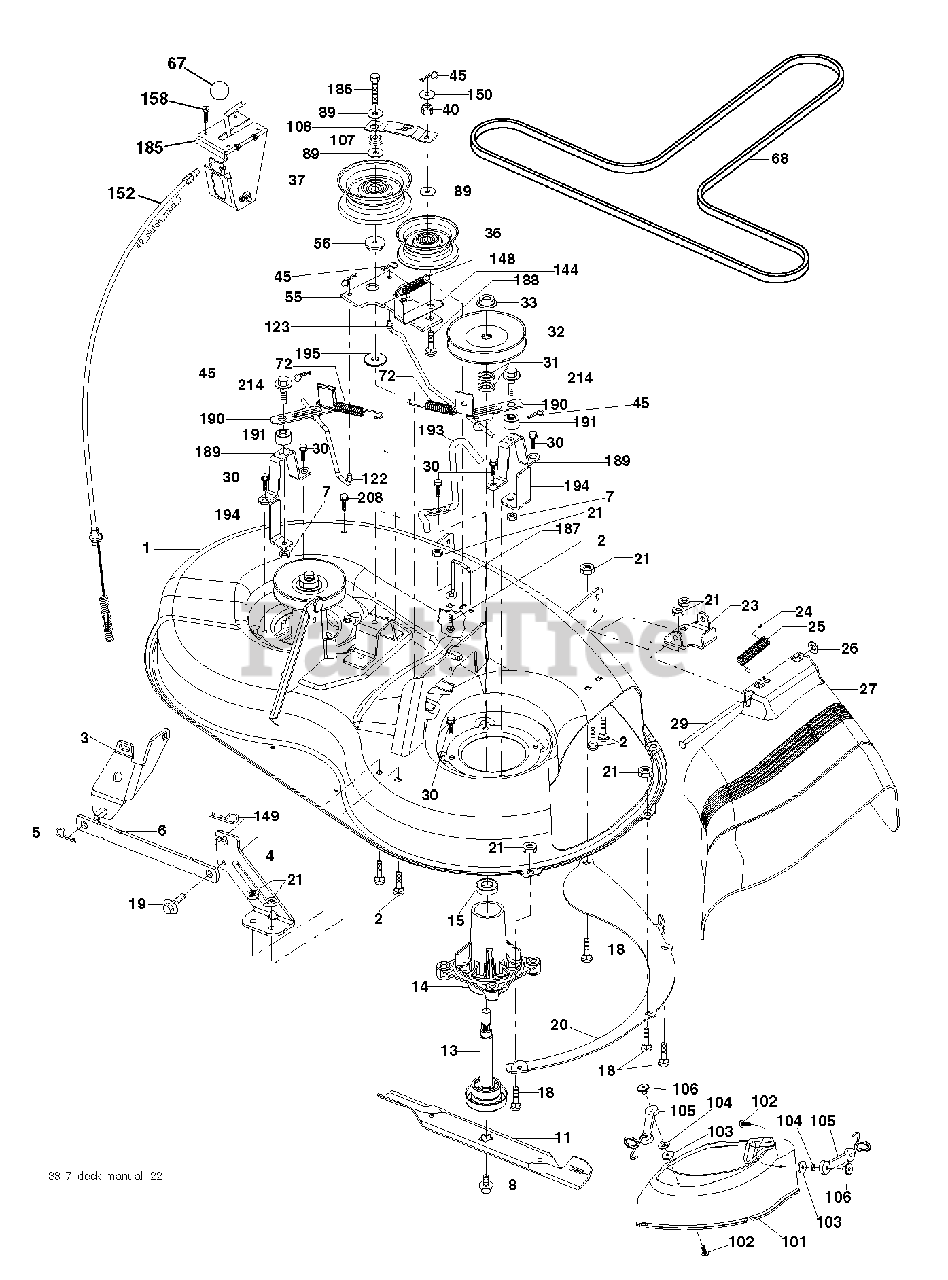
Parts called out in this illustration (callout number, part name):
1	DECK.WELDMENT.38"2005
2	BOLT
3	BRKT ASM SWAY BAR
4	BRACKET DECK SWAY BAR 38"/42"
5	RETAINER-SPRNG RB
6	BAR SWAY DECK
7	NUT.71038.31-18.HEX.NYLOCK
8	BOLT.WASHER.ASM.7/16-2
11	BLADE 38" PREMIUM
13	SHAFT.ASM.MDRL.N/GREASE.38
14	HOUSING MANDREL
18	BOLT
19	BOLT SHD 5/16-18
20	BAFFLE VORTEX
21	LOCKNUT
23	BRKT.DEFLECTOR.38"2005+
24	CAP-SLEEVE LT
25	SPRING.TORSION.DEFLECT
27	Deflector Shield, 38-7/97cm
29	ROD.HINGE
30	SCREW, WASHER HEAD
31	WASHER.SPACER.MANDREL
32	PULLEY MANDREL
33	NUT.FLANGE.LOCK.TOP
36	FLAT IDLER PULLEY
37	PULLEY.IDLER.FLAT.UNPLATED
40	LOCKNUT
45	RETAINER M
56	SPACER.RETAINER.MOWER
67	KNOB T (3/8 HOLE)
68	V-BELT.MOWER.38"2005+
72	SPRING.BRAKE.RETURN.38"
89	WASHER
106	WELDNUT
107	SPACER.IDLER.ARM
108	STIFFENER.IDLER.ARM
122	ROD, BRAKE LH LINK
123	LINK.BRAKE.38"RIGHT
148	IDLER RETURN SPRING
149	SPRING.RETAINER.YELLOW.ZINC
150	WASHER LT
152	CABLE.CLUTCH.38".SERVICE
158	SCREW
185	HEAD ASM. CABLE CLUTCH
186	SCREW.HXWSH.3/8
188	BOLT, CARRIAGE IDLER
189	STAND, BRAKE
190	ARM, BRAKE
191	SPACER, BRAKE
193	KEEPER BELT RH MANDREL
194	GUARD BRAKE
195	WASHER 12/32X2X10GA
208	SCREW 3/8-16X1/2
214	BOLT/WASHER ASM 5/16-18
